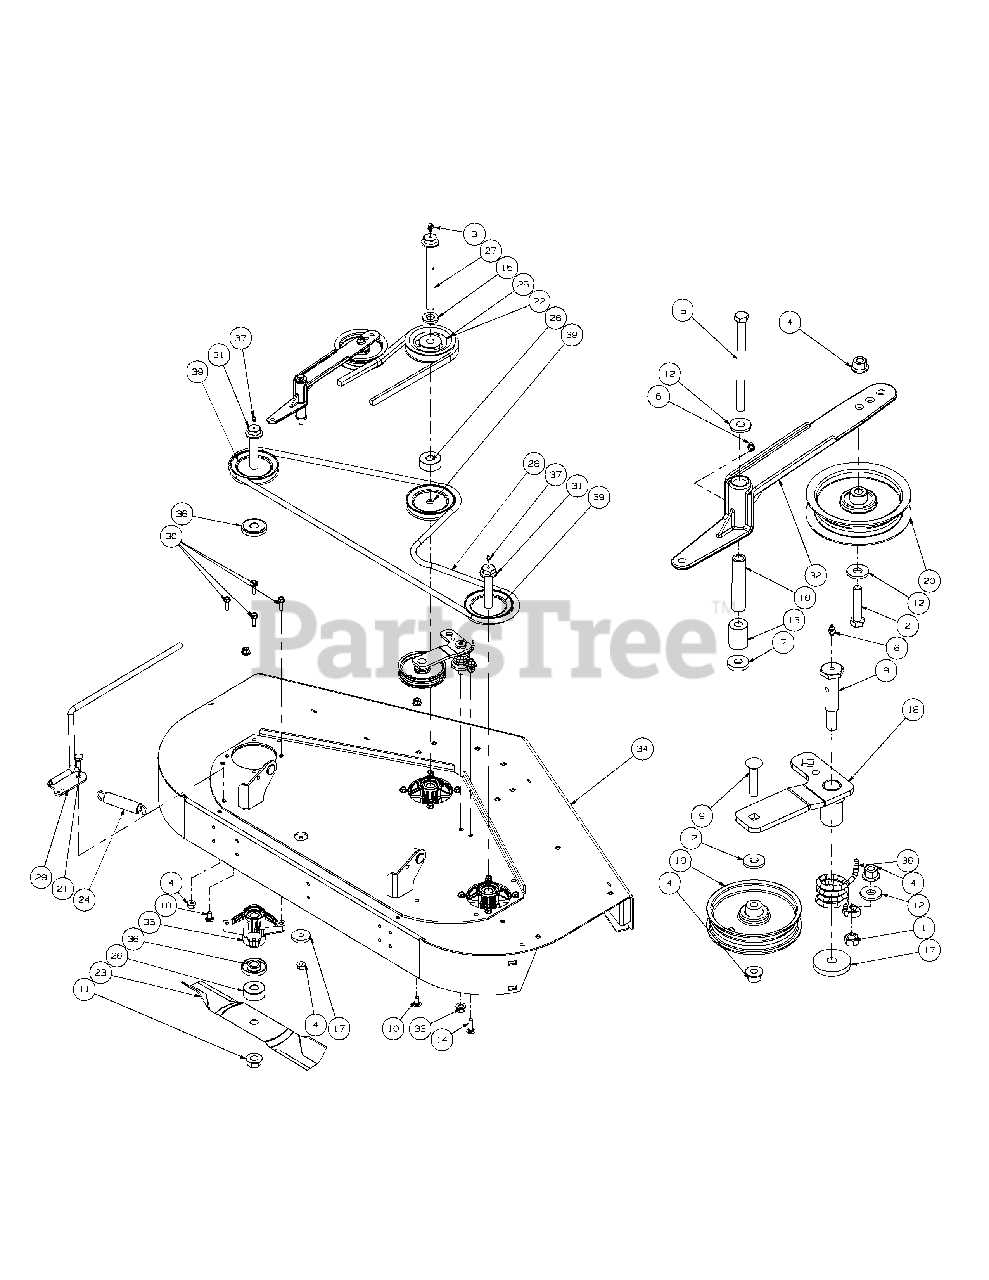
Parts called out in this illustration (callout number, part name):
1	Hex Nut 3/8-16
2	Hex Cap Screw, 3/8-16 x 1.75
3	Grease Fitting, 90
4	Hex Nut, 3/8-16 Flange Lock
5	Hex Cap Screw, 3/8-16 x 5.00
6	Grease Fitting, 1/4-28 x 3/16
7	Idler Washer
8	Shoulder Screw, 7/16-14
9	Hex Carriage Screw, 3/8-16, 1.75
10	Carriage Bolt 3/8-16 x .75
11	Hex Flange Nut, 3/4-16
12	Flat Washer, .406 ID x 1.0 OD x .105
13	Spacer, .39 ID x .875 OD x 1.10
14	Carraige Screw, 3/8-16 x 1.25
15	Spacer, .812 ID x .218
16	Spacer, .39 ID x .625 OD x 2.75
17	Flat Washer, 7/16 ID x 1.75 OD
18	Idler Arm Assembly, Deck Spindle
18	Bearing
19	Flat Pulley
20	Idler Pulley, 4.06 OD
21	Shoulder Screw, .50 x .27, 3/8-16
22	V-Pulley, 4.75 OD
23	Hi-Lift Blade, 17.0
24	Extension Spring, .98 OD x 5.00
25	V-Belt, B-Section
26	Spacer .760 ID x 2.00 OD x 0.790
27	Spindle Bolt, 3/4-16 x 7.155
28	V-Belt, A-Section
29	Spring Tension Rod Assembly
30	Self Tapping Screw 5/16-18 x 1.00
31	Spindle Bolt 3/4-16 x 5.37
32	Idler Arm Assembly, Top
33	Nut, 7/16-20, FlangeLock
34	Deck Assembly, 48"
35	Spindle Assembly
36	Idler Torsion Spring
37	Grease Fitting
38	Spindle Spacer
